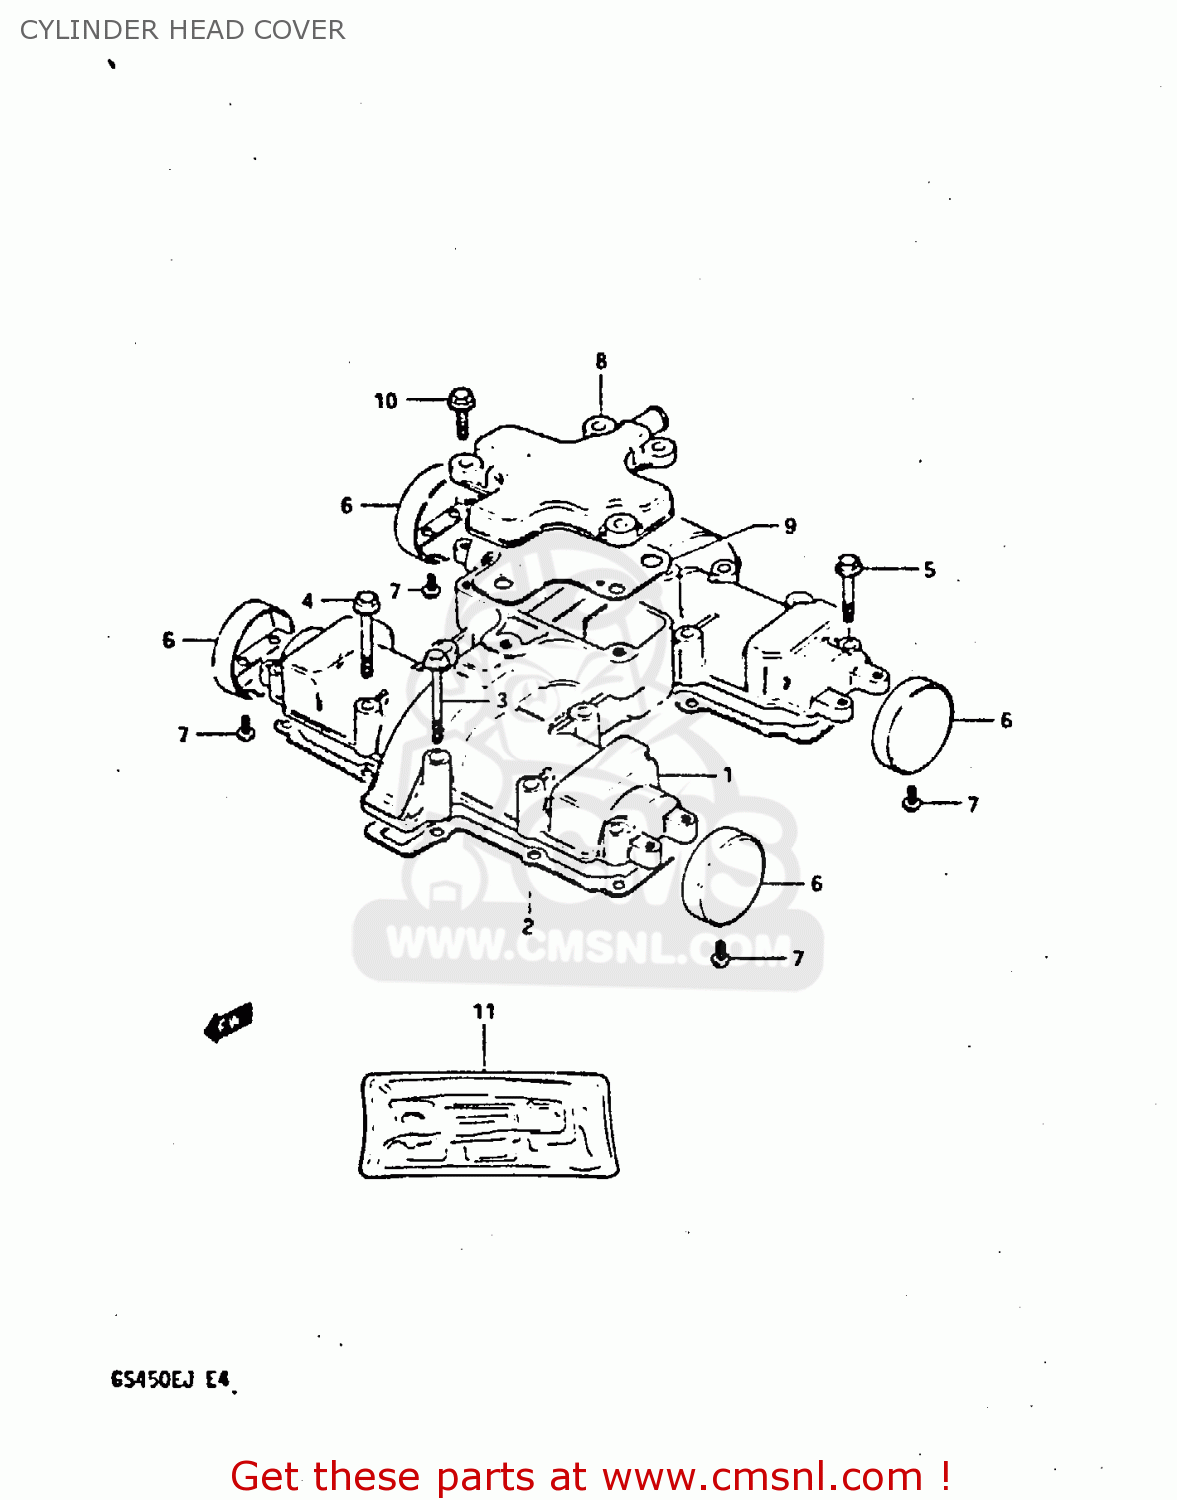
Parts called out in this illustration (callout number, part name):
1	COVER,CYLINDER HEAD
2	GASKET,CYLINDER HEAD COVER (MCA)
3	BOLT (6X45)
4	BOLT
5	BOLT 6X30
6	CAP,CYLINDER HEAD COVER
7	SCREW
8	COVER,BREATHER
9	GASKET (MCA)
10	BOLT
11	GASKET SET
